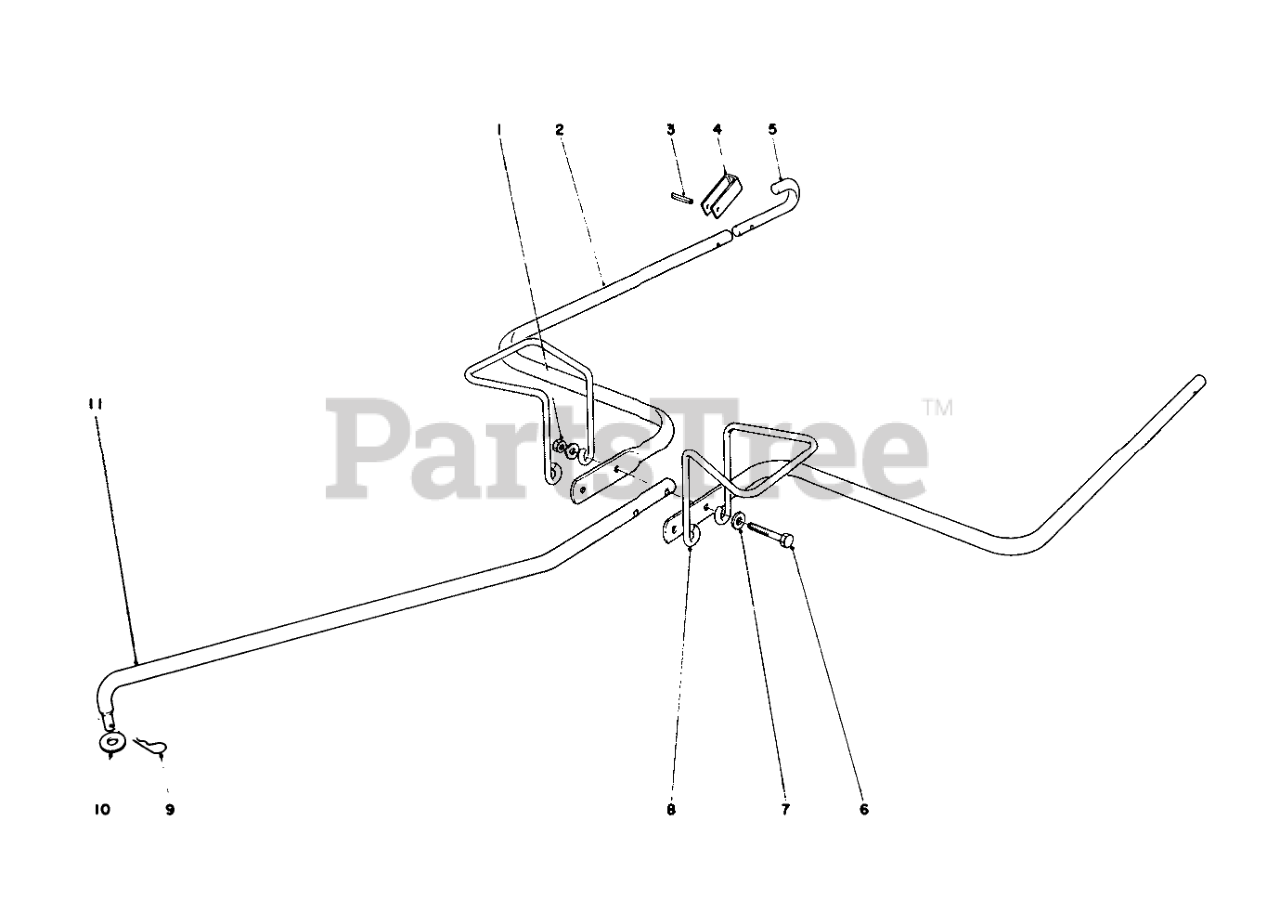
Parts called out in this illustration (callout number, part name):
1	NUT-LOCK, CONE
2	HITCH ARM
3	PIN-ROLL, SLOT
4	HITCH LOCK
5	HOOK HITCH ARM
6	SCREW-HH
7	WASHER-FLAT
8	Support Bag
9	PIN-COTTER
10	PUSH NUT
11	POLE HITCH
